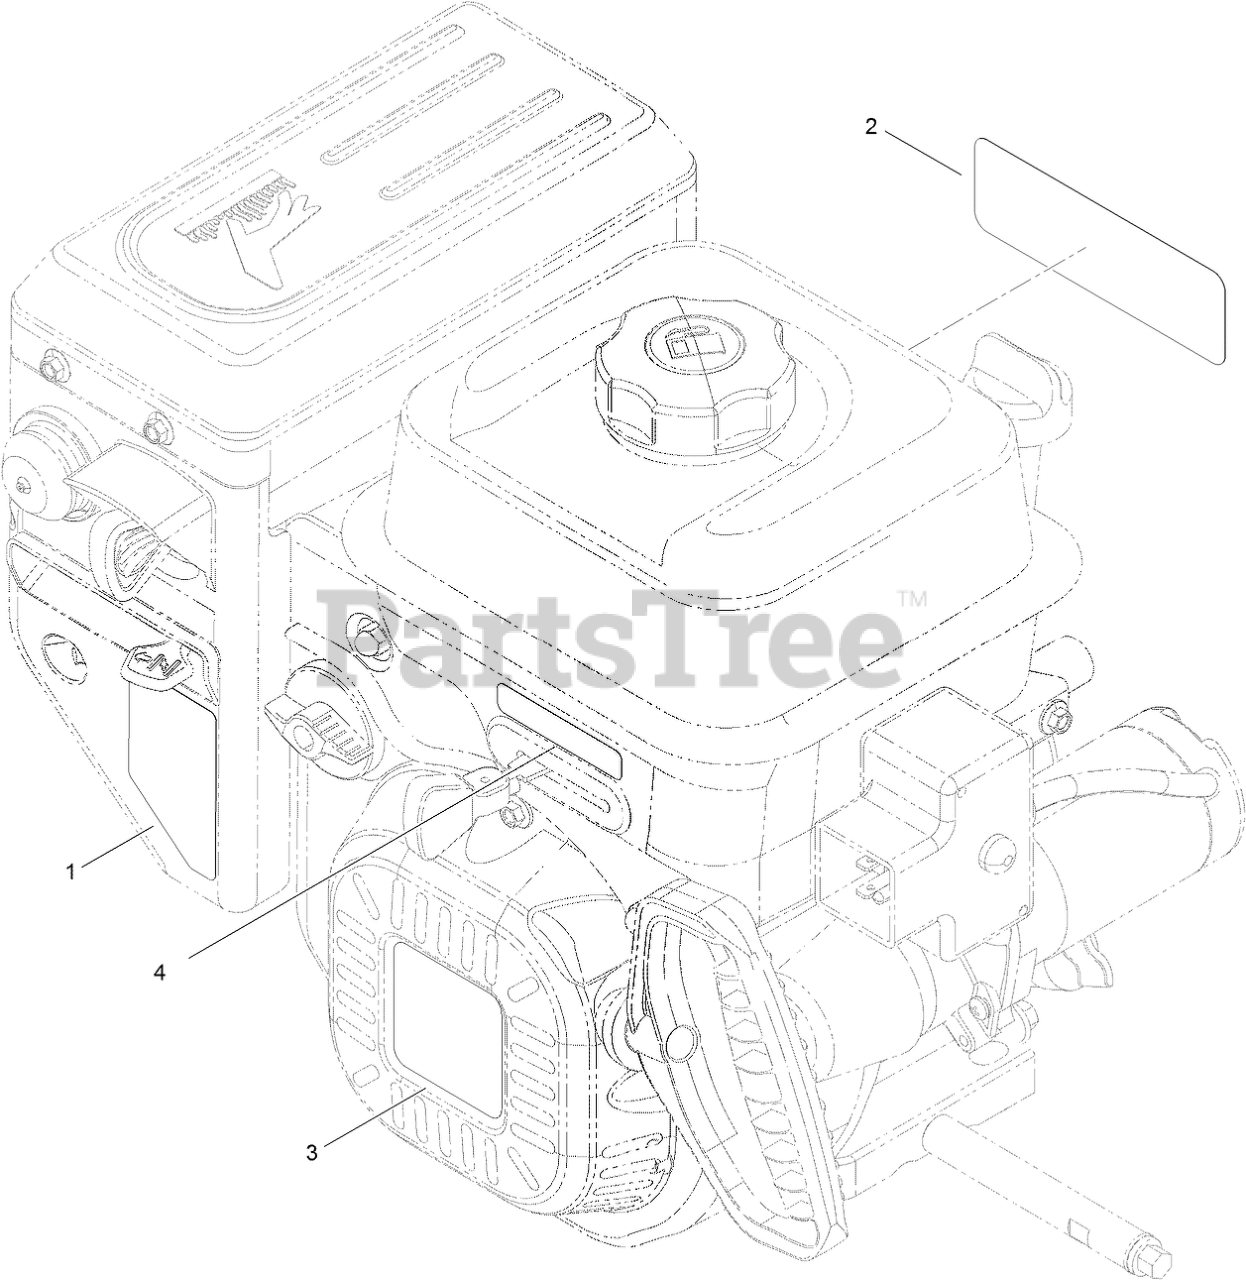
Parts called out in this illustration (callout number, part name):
1	DECAL-CONTROL, ENGINE
2	DECAL-ENGINE SERIES, G250
3	DECAL-RECOIL, G250
4	DECAL-THROTTLE
